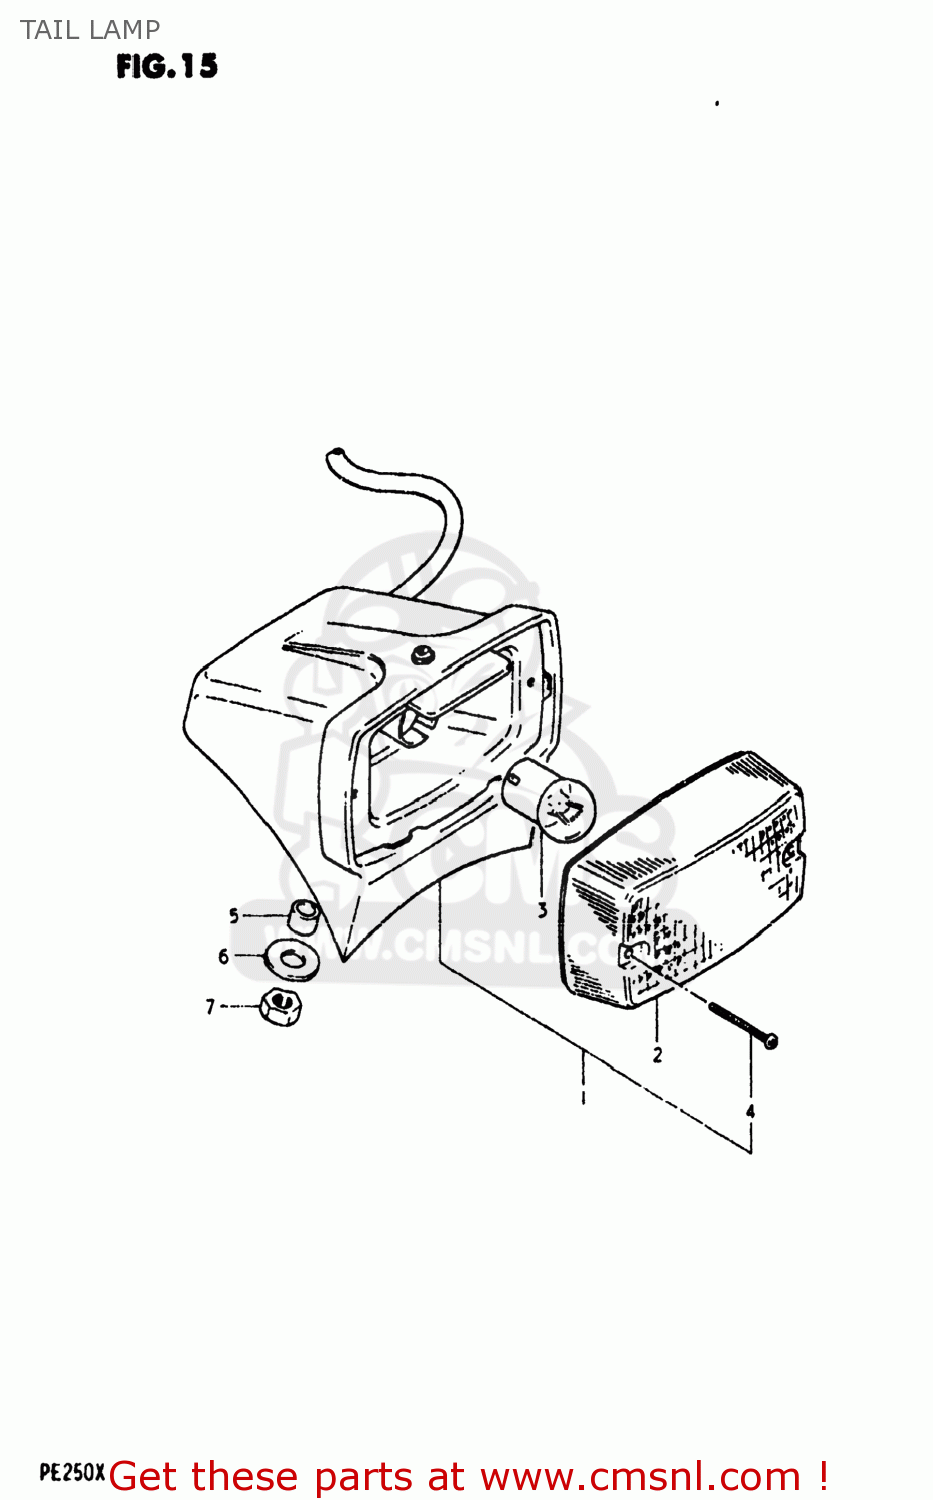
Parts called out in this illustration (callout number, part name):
1	LAMP ASSEMBLY,REAR COMBINATION
2	LENS
3	BULB(6V5W,TOKAI DENSO)
4	SCREW,REAR COMBINATION LAMP LENS
5	SPACER (6.1X9X9)
6	WASHER
7	NUT
